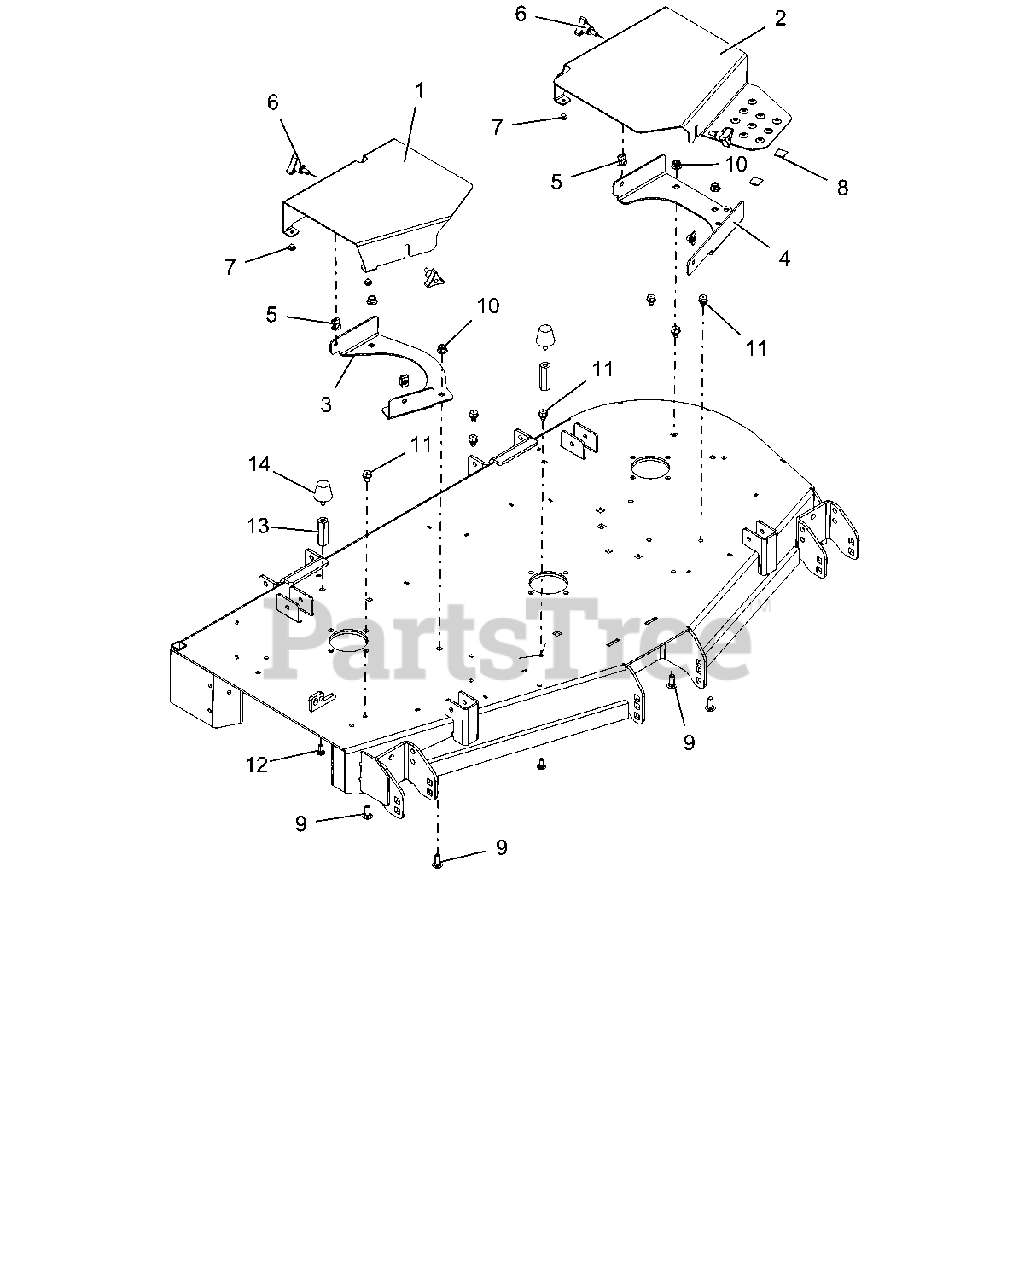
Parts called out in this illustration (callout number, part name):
1	GUARD, RH DECK - RED
2	GUARD, LH BELT - RED
3	BRKT, RH BELT GUARD MTG - RED
4	BRKT, LH BELT GUARD MTG - RED
5	NUT-CLIP RETAINER 5/16-18X.56
6	KNOB,WING STUD 5/16-18 X .75
7	BUMPER GROMMET
9	BLT-RDHDSQNK .38-16X1.00 G5YZ
10	@NUT-LK-NYL-FLG .38-16 YWZC
11	@SCR-TAP .38-16X.50 HWH TR YWZ
12	BLT,RDHDSQNK .31-18X.75 LOCTIT
13	NUT, .31-18X2.25 LG COUPLING
14	BUMPER, RUBBER CONE,STUD MOUNT
